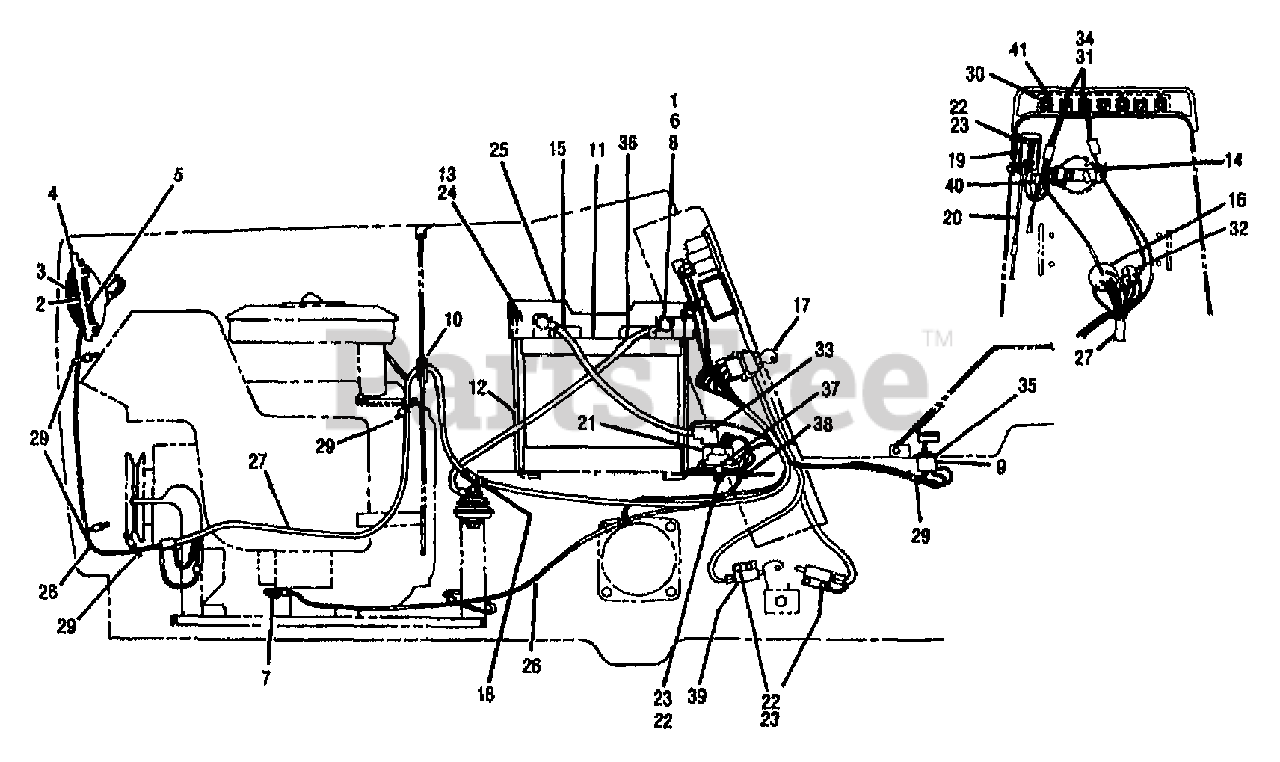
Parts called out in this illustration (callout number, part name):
1	NUT-HEX 1/4-20 ZP
2	RIVET-POP 3/16 X 5/8
3	HEADLAMP
4	PLATE-RETAINER
6	WASHER-LK .25 ZP
7	NUT-HF/LK 1/4-20 ZP
8	SCR-HH 1/4-20X.625 G5 ZP
9	SWITCH
10	BUSHING
11	BATTERY
12	BOLT-HOOK
13	WASHER-FLAT 1/4 SAE
14	AMMETER 20-0-20
15	CABLE-BATTERY (+)
16	SWITCH-IGN
17	KEY-IGNITION
18	TUBING
19	RELAY
20	HARNESS-CRUISE
21	SOLENOID
22	SCR-TRUSS #10-24 X 5/8
23	NUT W/LKWASHER 10-24 ZP
24	NUT-HT LK 1/4-20
25	BATTERY-HOLDDOWN
26	CABLE-STARTER
27	HARNESS-MAIN
28	HARNESS-HEADLIGHT
29	TIE-CABLE NYLON BLACK
30	STRIP-SEALING
31	ASSM-LAMP
32	SWITCH-PTO
33	NIPPLE-ELECTRICAL
34	BULB (MFG NO. GE 73)
35	SEAL-SWITCH
36	CABLE-BAT (-) TO ENG MNT
37	CONDENSOR
38	GROMMET-FLIP
39	SWITCH
40	SWITCH-CRUISE
41	SCR-PHP M6-32X.38 ZP
